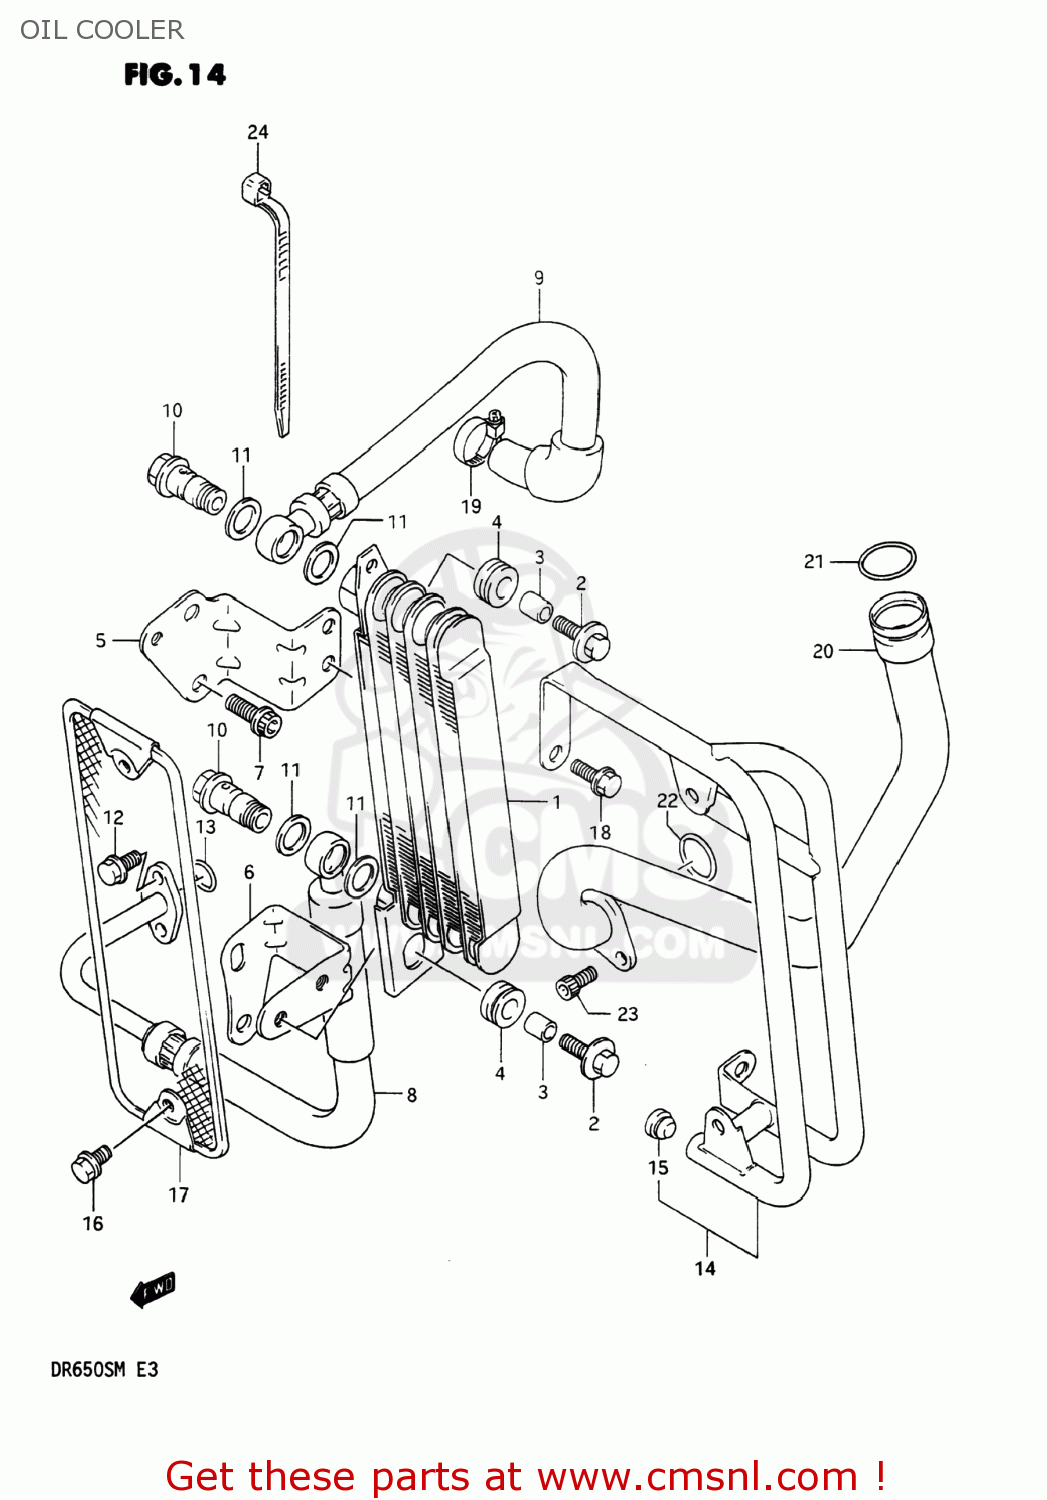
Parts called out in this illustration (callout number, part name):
1	COOLER ASSEMBLY,OIL
2	BOLT 6X20
3	SPACER (6.8X10X10)
4	CUSHION
5	BRACKET,OIL COOLER UPR
6	BRACKET,OIL COOLER,LOWER
7	BOLT
8	HOSE,OIL COOLER NO.1
9	HOSE,OIL COOLER NO.2
10	BOLT UNION
11	GASKET(14X20X1.5) (NAS)
12	BOLT
13	O RING(D:2.4,ID:12.3)
14	GUARD,OIL COOLER
15	PLUG(OD:13)
16	BOLT 6X12
17	BUMPER,OIL COOLER
18	BOLT
19	CLAMP
20	PIPE COMP,OIL RETURN
21	O RING(D:3.7,ID:21.7)
22	O RING(D:2.4,ID:23.7)
23	BOLT
24	CLAMP(L:125)
